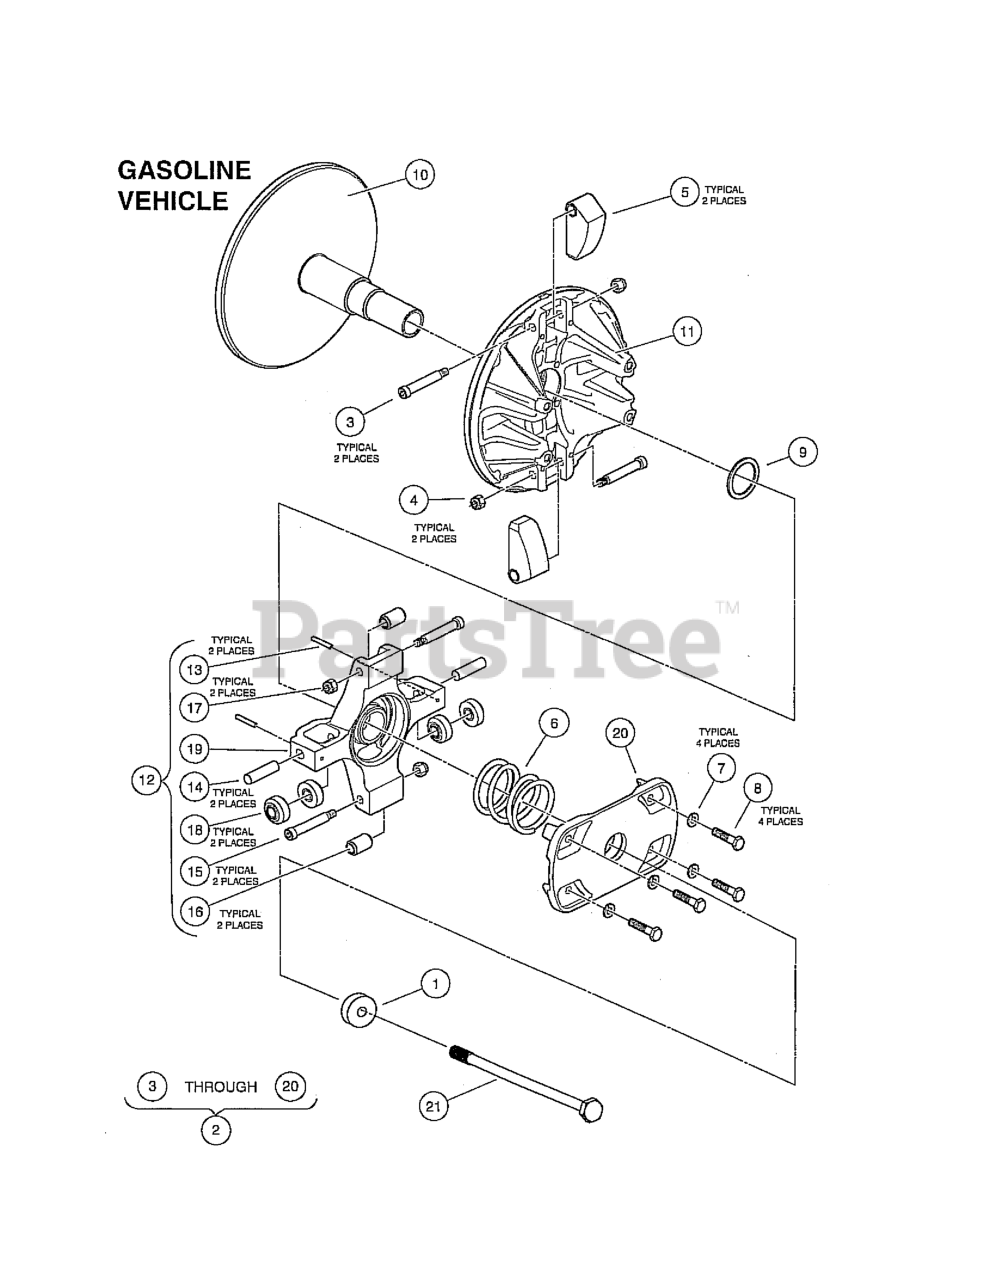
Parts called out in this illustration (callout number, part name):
1	WASHER, STEPPED, CVT PRIMARY
2	CVT, PRIMARY GAS
3	SCREW, SHLDER HEX, .312 X 1.75
4	NUT, LOCK HEX, 1/14-20, FLEXLC
5	SUB ASSY, WT CLUTCH, GAS
6	SPRING, COMPRESSION, PRIMARY
7	WASHER, LOCK, H SPRING, 1/4
8	SCREW, CAP, HEX HD, 1/4 X 1.25
9	SHIM, 1.63 X 1.33
13	PIN, SPRING SLOTTED,1.25 X 1.0
14	PIN, DOWEL, .375 X 1.50
15	SCREW, SHLDER HEX, .312 X 1.75
16	SUB ASSY, ROLLER WEIGHT
17	NUT, LOCK HEX, 1/14-20, FLEXLC
18	ROLLER, TORQUE, GAS
21	BOLT, M10X1.25X200 LOCTITE
